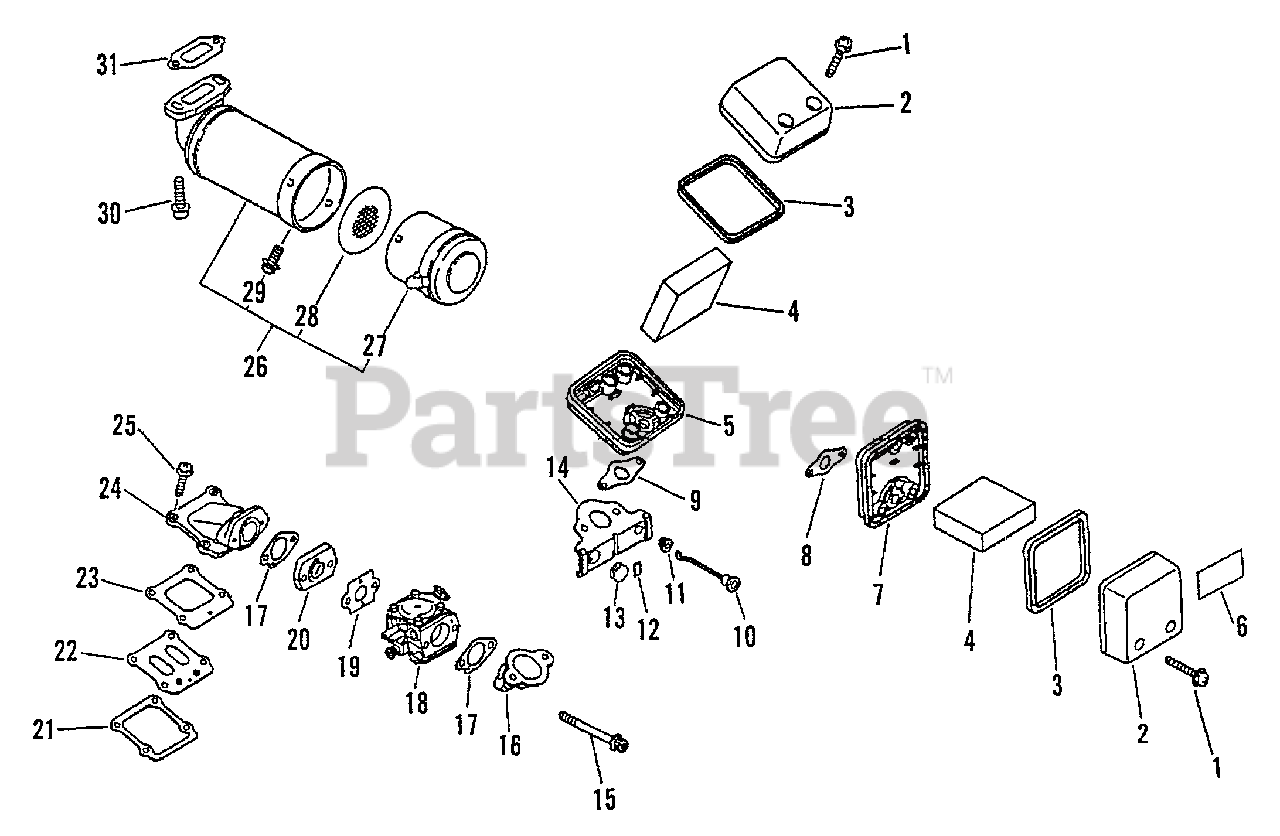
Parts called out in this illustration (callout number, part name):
1	SCREW 5×40
2	COVER, AIR FILTER
3	SEAL, CLEANER
4	FILTER, AIR
5	CASE, AIR FILTER
6	LABEL - CAUTION
7	CASE, AIR FILTER
8	GASKET, INTAKE
9	GASKET, CLEANER
10	ROD, CHOKE
11	GROMMET
12	LABEL - CHOKE
14	BRACKET, SWITCH
15	SCREW 5×60
16	ADAPTER, INTAKE
18	CARBURETOR - WT-233
19	GASKET, INTAKE
20	INSULATOR, INTAKE
21	GASKET, REED VALVE
22	VALVE ASSY, REED
23	GASKET, REED VALVE
24	ADAPTER, INTAKE
25	SCREW 5×18
26	MUFFLER
27	LID, MUFFLER
28	SCREW
29	SCREW 5×10
30	BOLT 5×14
31	GASKET, MUFFLER
